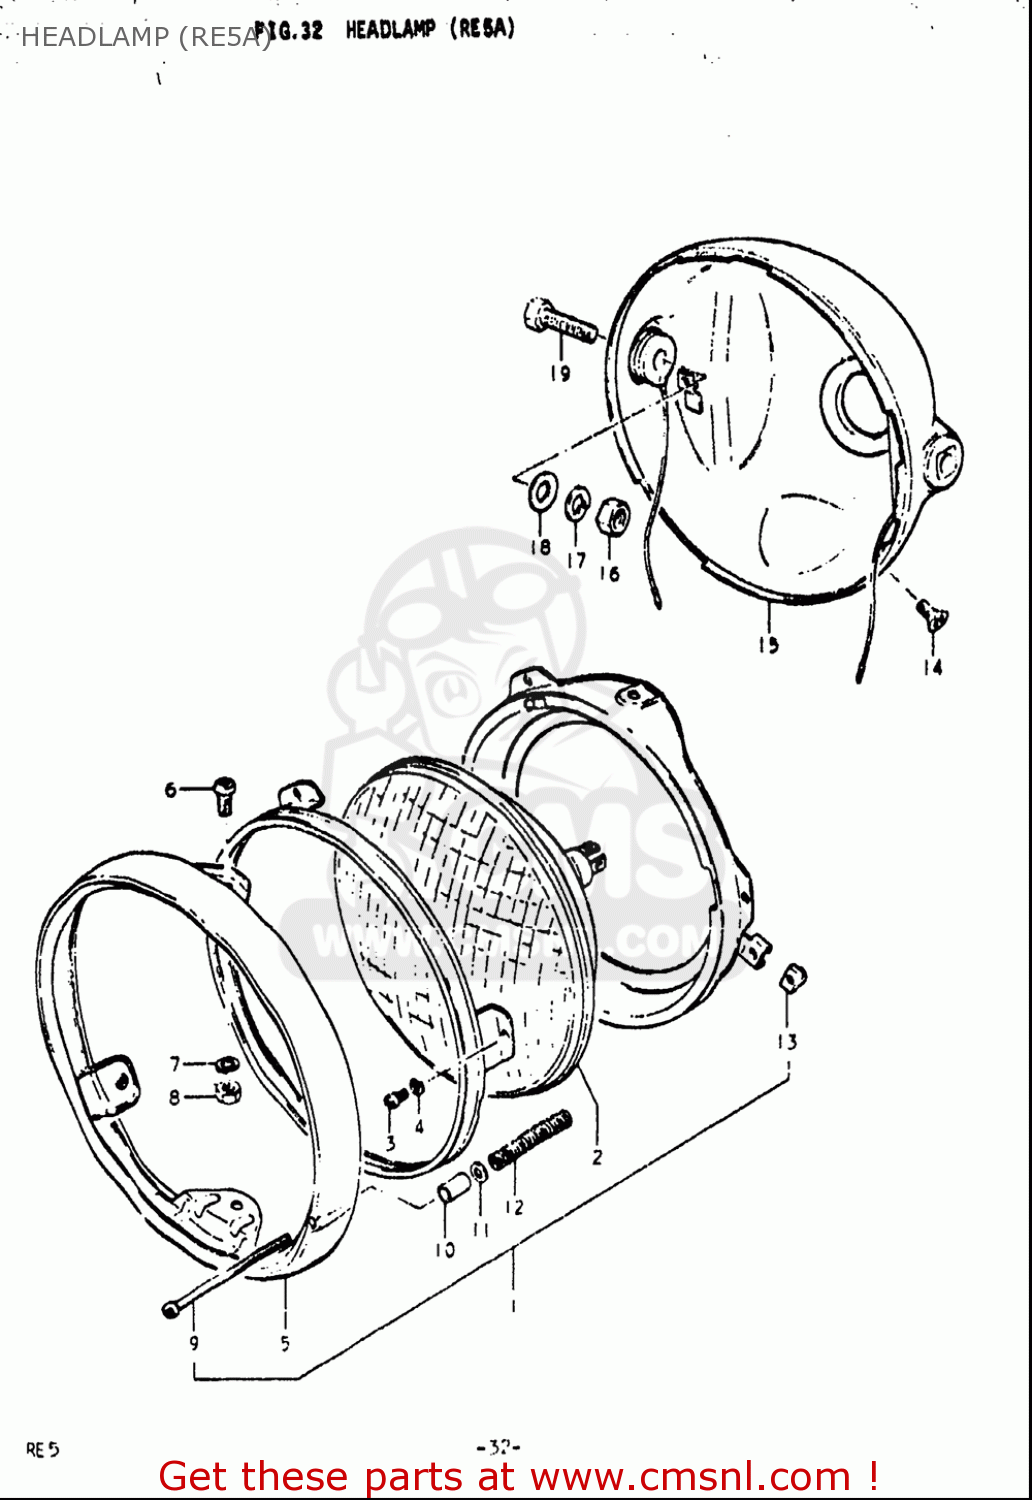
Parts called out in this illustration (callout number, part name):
3	SCREW
4	WASHER,LOCK
5	RIM,HEADLAMP
6	SCREW
7	WASHER,LOCK
8	NUT
9	SCREW
11	WASHER
13	NUT
14	SCREW
15	HOUSING,HEADLAMP
16	NUT
17	WASHER,LOCK
18	WASHER
19	BOLT
